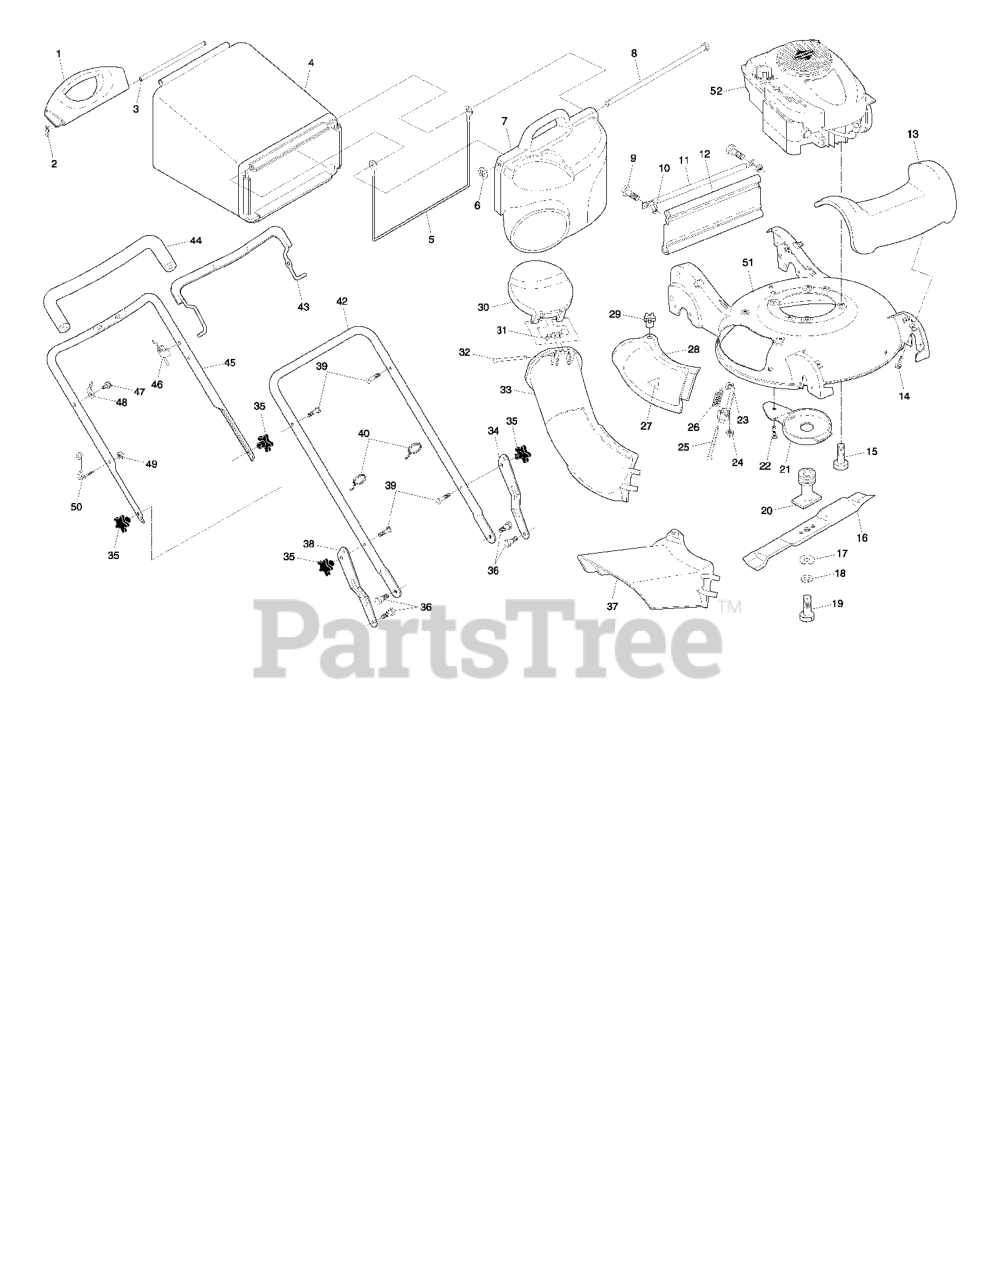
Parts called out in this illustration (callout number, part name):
1	HANDLE.GRASSBAG.REAR.H-GRAY
2	COTTER PIN (3 2)(2 2MC)
3	ROD.REAR.HANDLE.YELLOW
4	GRASSBAG
5	FRAME, GRASSBAG
6	E-RING
7	DOOR, GRASSBAG
8	ROD, PIVOT
9	BOLT T
10	LOCKNUT.NYLOC.1/4-20
11	TUBE, REAR SKIRT
12	SKIRT, REAR
13	COVER, FRONT
14	SCREW
15	BOLT 3/8-16X1-1/8
16	21"BLADE (2004 MODEL 55R21HV)
17	WASHER,HARDEN
18	LOCKWASHER
19	SCREW.HX.HEAD.3/8-24
20	ADAPTER, BLADE
21	DEBRIS SHEILD
22	SCREW 1/4X20
23	BRACKET.ASM.HINGE
24	LOCK NUT
25	ROD.HINGE.1/4"3.82"
26	SPRING.MULCH.DOOR
27	DECAL HYT
28	MULCHER DOOR
29	KNOB.MULCH.DOOR
30	CHUTE.DOOR.21.HV.H-GRAY
31	SPRING
32	ROD.HINGE.1/4"3.82"
33	DISCHARGE CHUTE PLASTIC
34	BRACKET
35	KNOB.HANDLE.STAR.HUSQ.GRAY
36	SHOULDER BOLT
37	GUARD.CLIP.ON.21.HV.GRAY
38	BRACKET ADJ LOWER HNDLE RH
39	HANDLE BOLT
40	TIE GUIDE
42	HANDLE.LOWER.GREY
43	BAIL CONTROL
44	GRIP.HANDLE.FOAM.WIDE.(1 SIDE)
45	HANDLE.ASM.UPPER.W/GRIP
46	ASSY ZONE CONTROL
47	SCREW
48	BRACKET
49	HEX NUT
50	GUIDE.ROPE.WALK.MOWER
51	KIT.HSG.ASM.21".HV.ORNG
